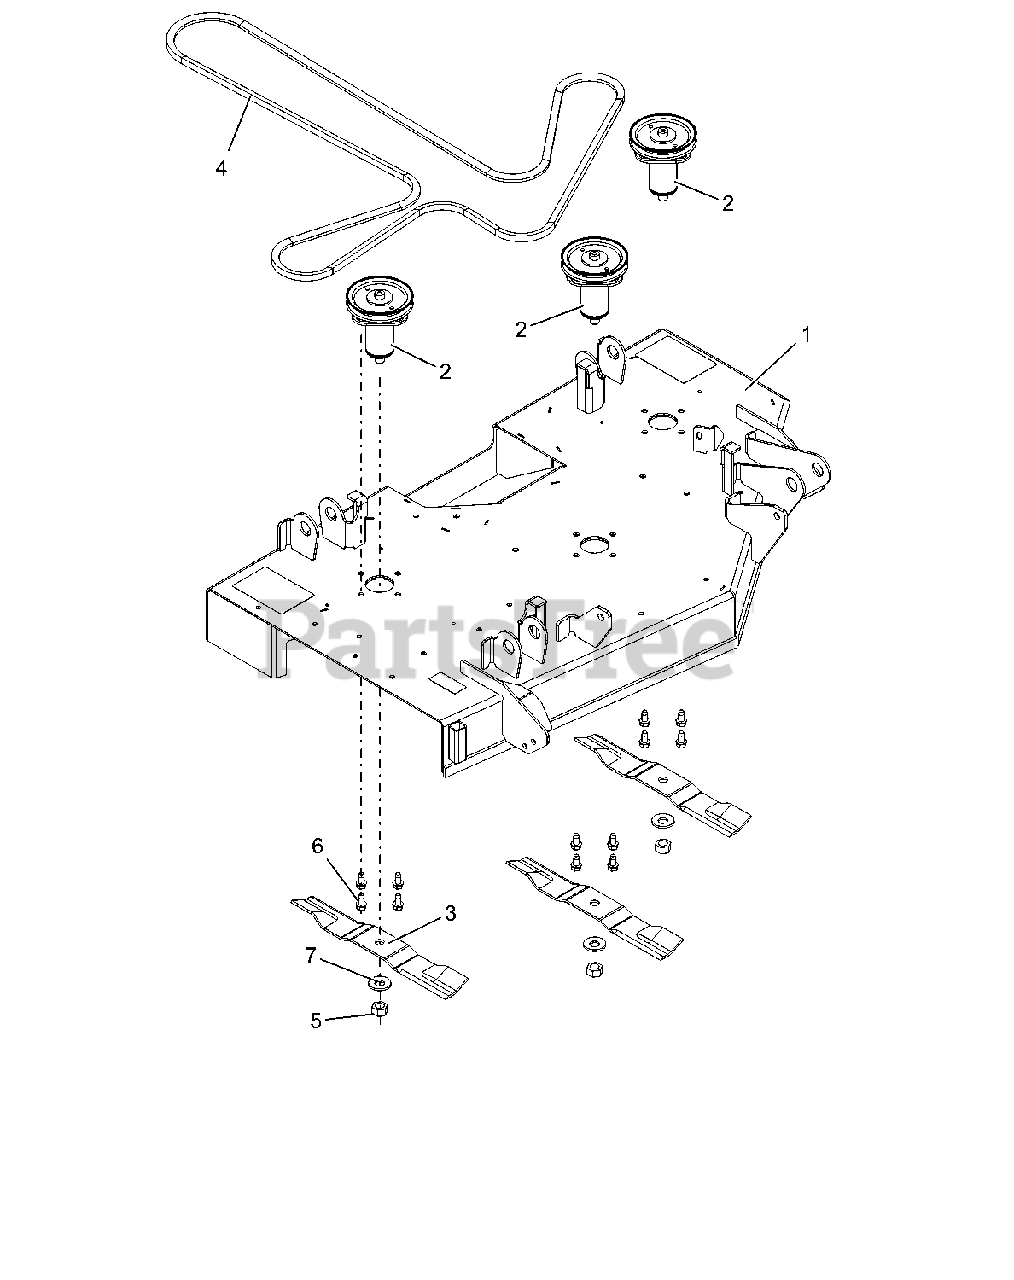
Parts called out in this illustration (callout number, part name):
1	KIT, 42" ARIENS DECK W/DECALS
2	KIT, DECK SPINDLE ASM-IKON-ZTX
3	BLADE, MOWER 15.00"
4	V-BELT, 4L-WRAPPED
5	NUT-HEX .62-18 YWZC
6	@SCR-TAP .38-16X.75 HWH TR YWZ
7	WSHR-BLVL .669X1.535X.138
